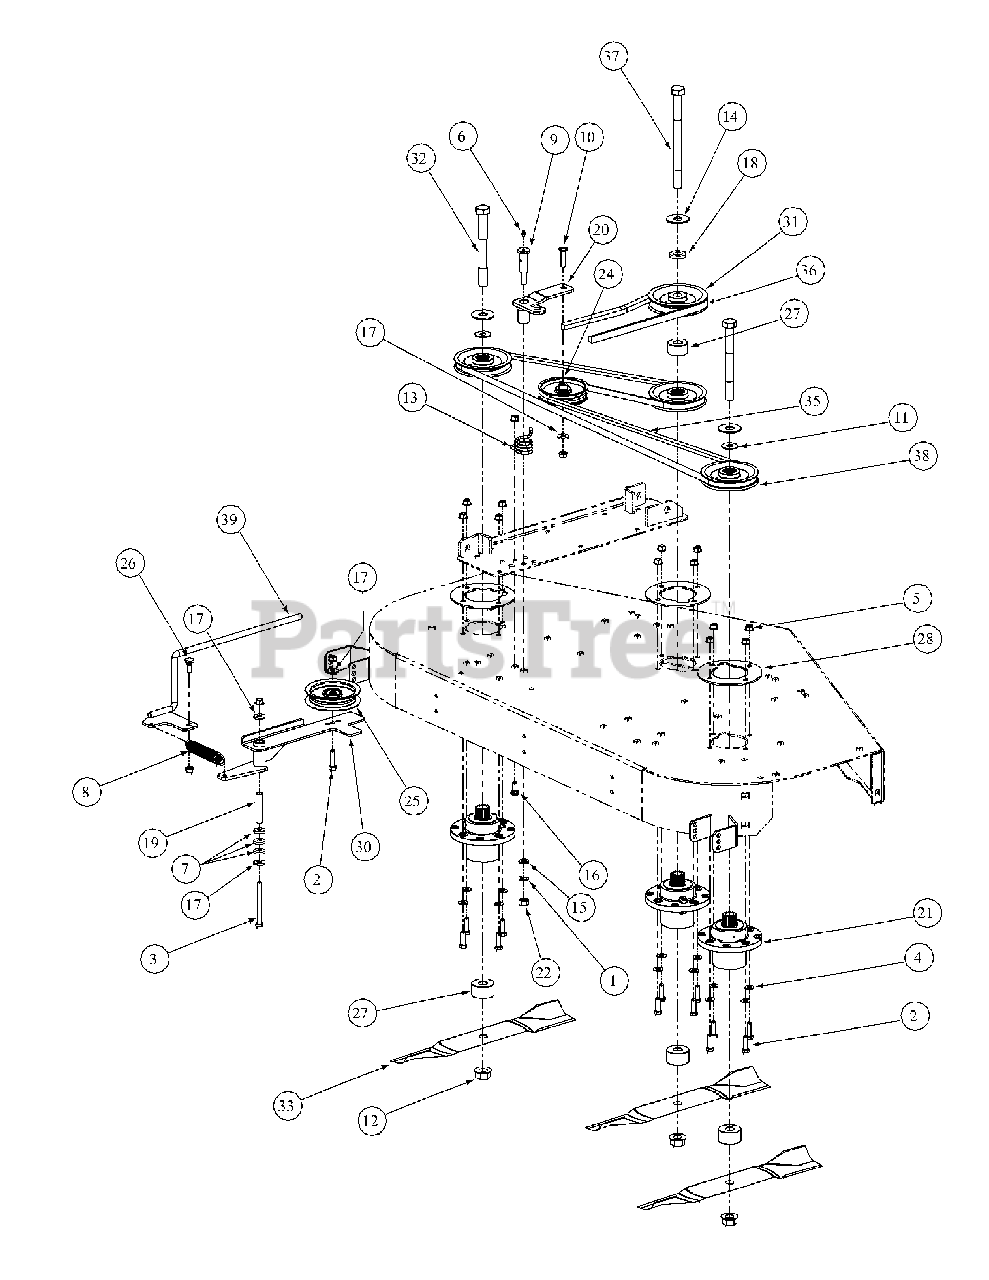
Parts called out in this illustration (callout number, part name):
1	Lock Washer, 7/16
2	Hex Cap Screw, 3/8-16 x 1-1/2
3	Hex Cap Screw, 3/8-16, 4.00
4	Flat Washer, 3/8
5	Hex Nut, Flange Lock, 3/8-16
6	Grease Fitting, 1/4-28 x 3/16
7	Idler Washer
8	Extension Spring, 1.0 OD x 5.125
9	Shoulder Screw, 7/16-14
10	Hex Carriage Screw, 3/8-16, 1.75
11	Spacer, .812 ID x .218 LG
12	Flange Hex Nut, 3/4-16
13	Torsion Spring Idler
14	Flat Washer, .781 ID, 2.00 OD, .105
15	Flat Washer, .469 ID, .875 OD, .105
16	Carriage Bolt, 3/8-16 x 1
17	Flat Washer, .406 ID, 1.0 OD, .105
19	Spacer, .39 ID x .625 OD x 2.75
20	Idler Arm Assembly, Deck Spindle
21	Spindle Assembly, Aluminum Fab Deck
22	Hex Nut, 7/16-14
24	Flat Pulley
25	Idler Pulley, 4.06 OD w/Deep Plan Flanges
26	Shoulder Screw, .50 x .27 LG, 3/8-16
27	Spacer, .760 ID x 2.000 OD x 1.1
28	Plate Support, Cast Aluminum Spindle
30	Idler Arm Assembly, Flat Top Bearing
31	V Pulley, 5.25 OD
32	Hex Cap Screw, 3/4-16, 7.00
33	Hi-Lift Blade, 19.0, 0.756
35	V Belt, A Section x 114.3
36	V Belt, B Section x 87.3
37	Hex Cap Screw, 3/4-16, 9.00
38	V Pulley, 5.00 OD
39	Rod Fab Deck Spring Tension
